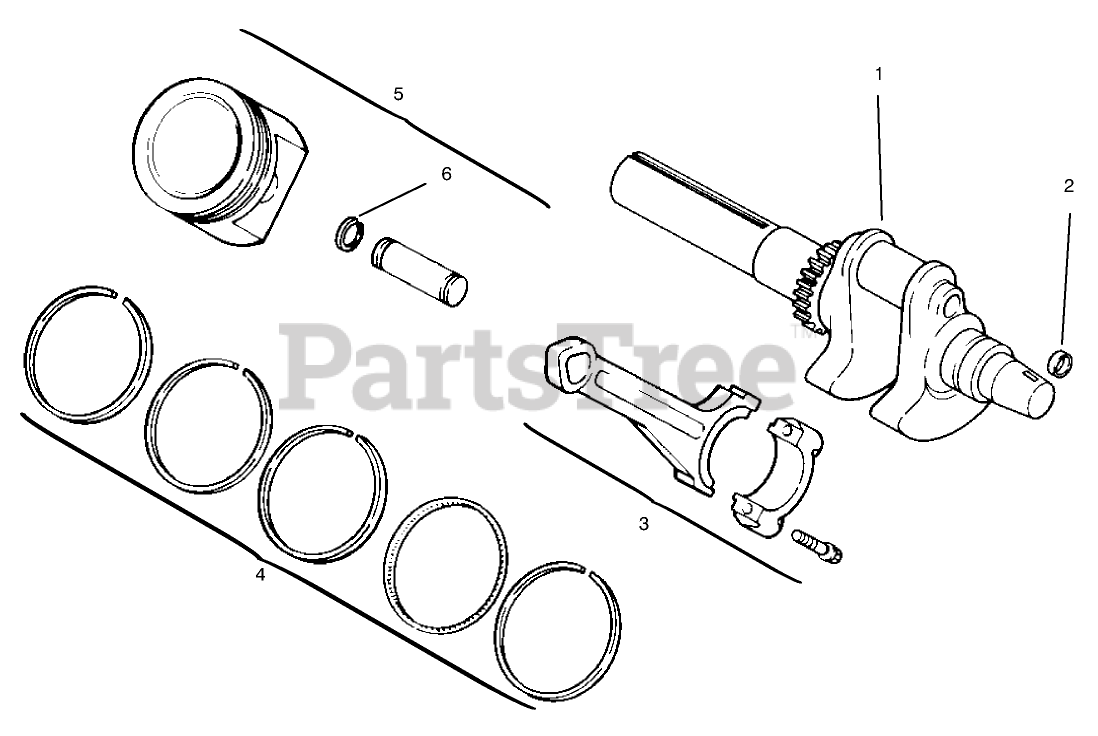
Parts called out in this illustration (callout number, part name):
1	Crankshaft
2	Plug-Cup
3	Connecting Rod STD
4	Ring Set(Std.)
5	Piston w/Ring Set (Std.) (Incl. Ref. # 4-6)
6	Retainer-Piston Pin
